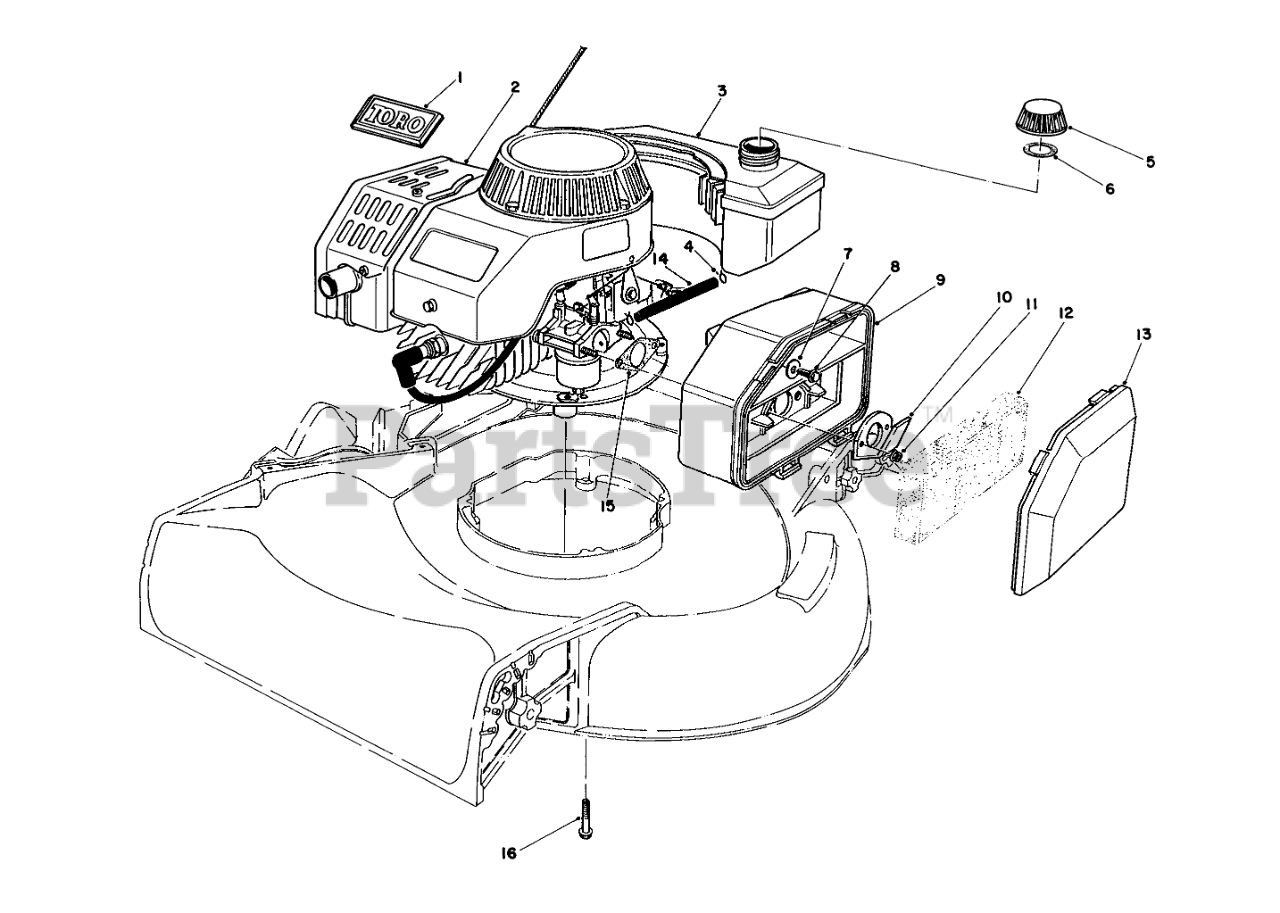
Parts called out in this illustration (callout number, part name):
1	TORO LOGO PLT
2	Engine
3	Fuel Tank Assembly
4	CLAMP-HOSE
5	Gas Cap Assembly (Incl. Ref. #6)
6	GAS CAP GASKET
7	WASHER-FLAT
8	SCREW-HH
9	AIR CLEANER
10	SPIT BACK DEFLECTOR
11	NUT-LOCK
12	FILTER
13	AIR CLEANER COVER
14	FUEL LINE
15	GASKET-AIR CLEANER
16	FLG SCREW,3/8-16X2.000
